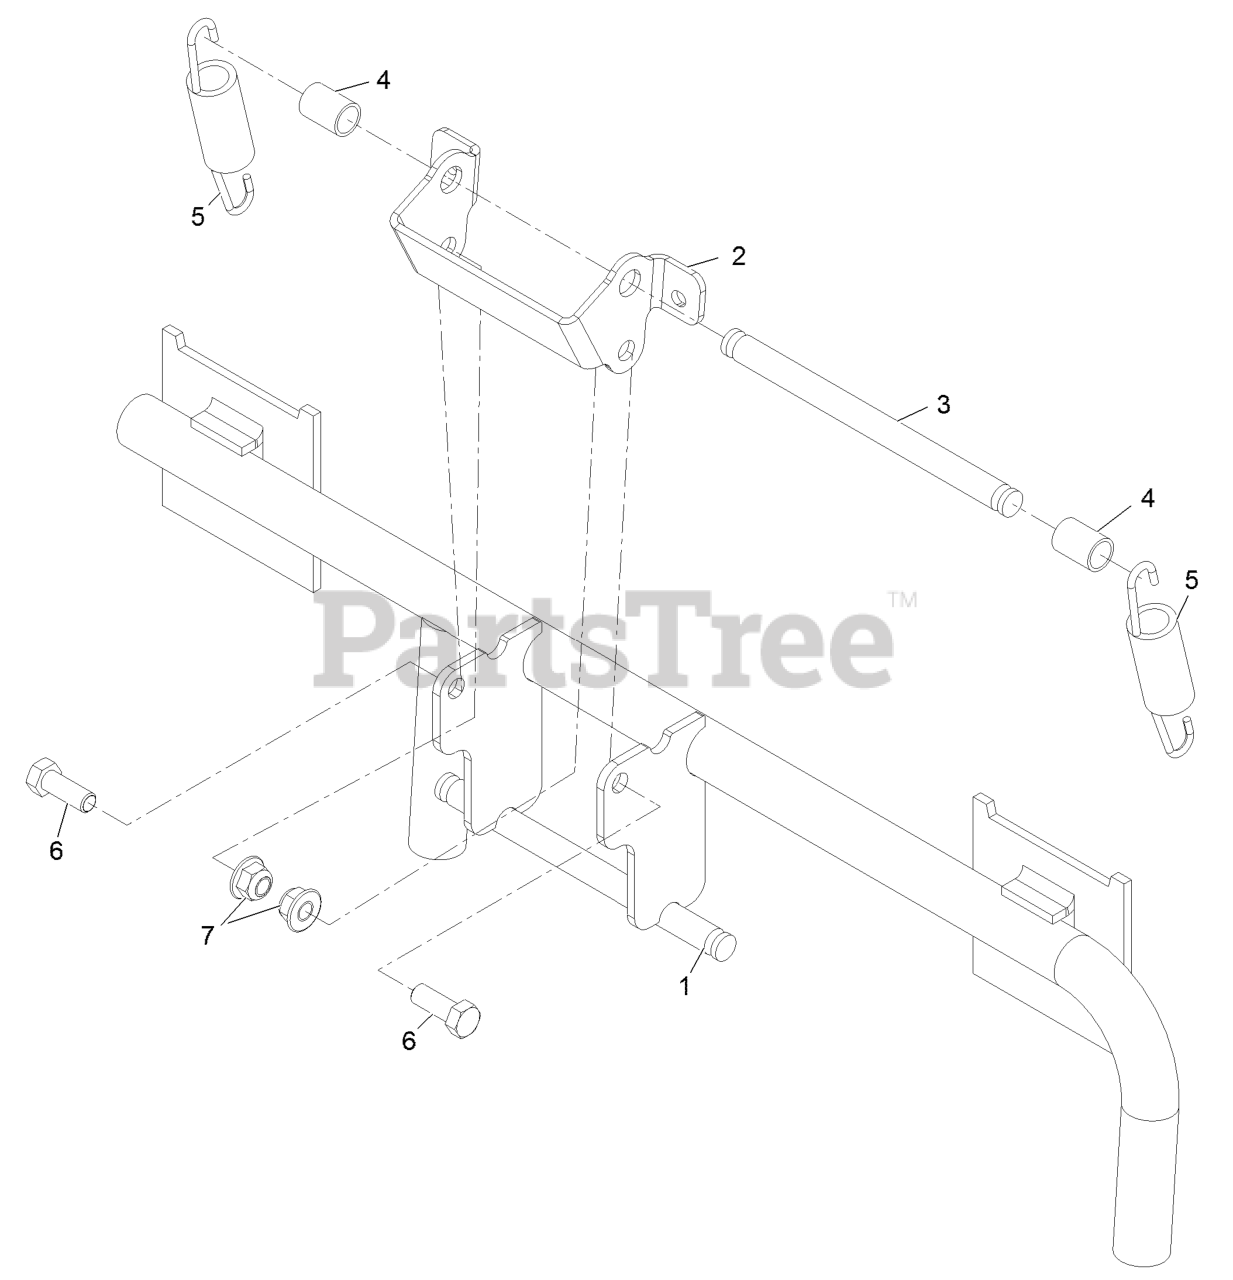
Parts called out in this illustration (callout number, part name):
1	WLD,BAGGER FRAME
2	HINGE,BAGGER TOP
3	PIN-SPRING
5	SPRING-EXTENSION
6	SCREW-HH
7	NUT-HF, NI
